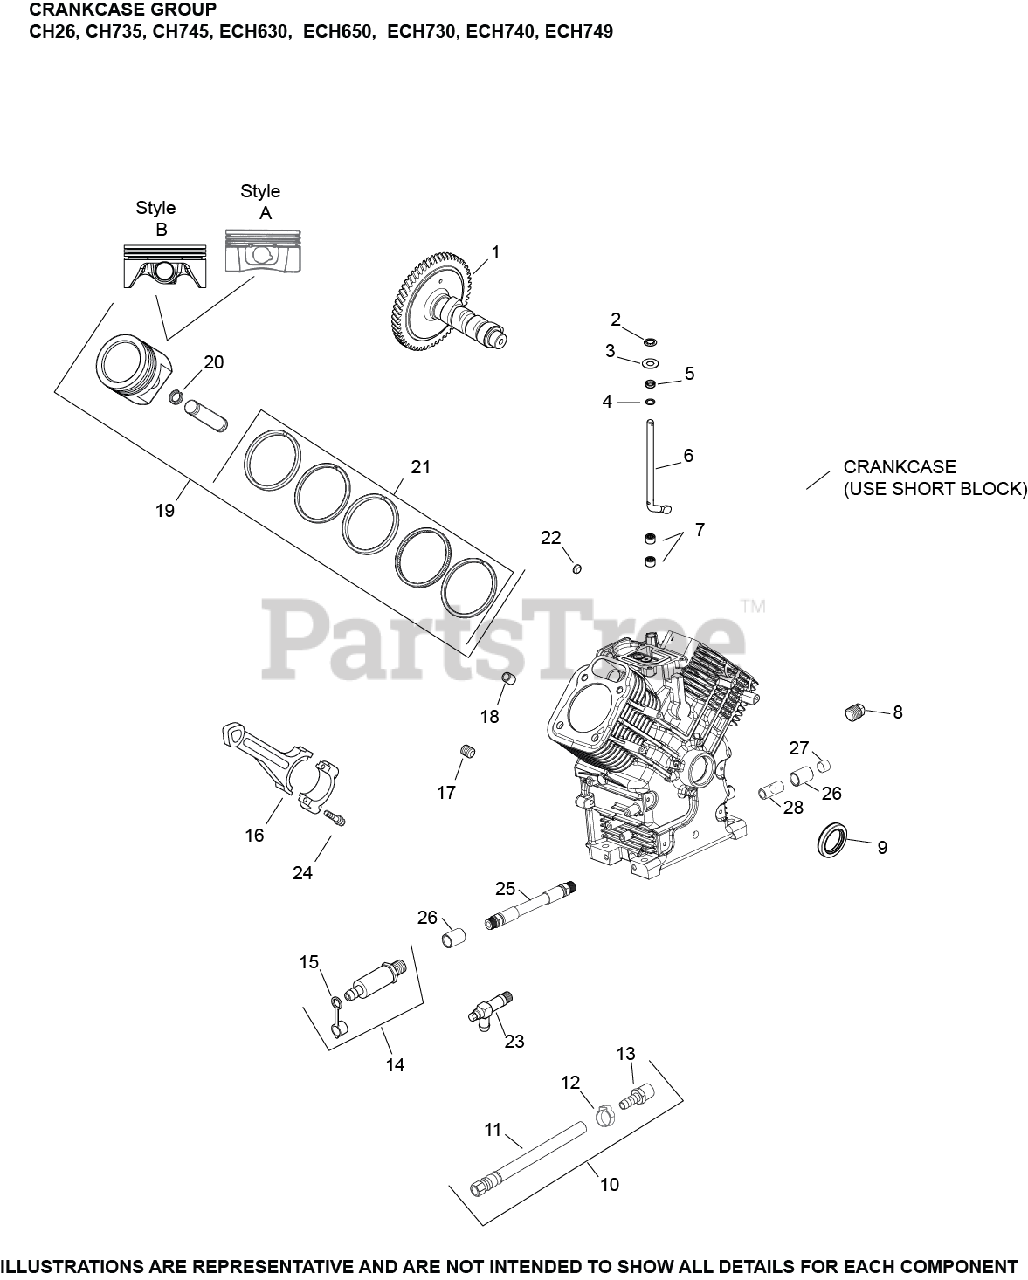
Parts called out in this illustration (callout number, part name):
1	KIT, CAMSHAFT
2	RETAINER, RING
3	WASHER, FLAT 9 MM
4	WASHER, FLAT 11/32"
5	SEAL, GOVERNOR CROSS SHAFT
6	SHAFT, GOVERNOR CROSS
7	BEARING, NEEDLE
8	PLUG, HD PIPE 3/8"
9	SEAL, OIL (HELIX LIP)
16	KIT, CONNECTING ROD ASSEMBLY USE 25 067 04-S
16	KIT, CONNECTING ROD ASSEMBLY (.25 mm)
17	PLUG, CTSK PIPE 1/8"
18	PIN, LOCATING
19	PISTON W/RINGS (STYLE B)(STD) - RING SET 24 108 26-S
19	PISTON W/RINGS (STYLE B)(.08) - RING SET 24 108 27-S
19	PISTON W/RINGS (STYLE B)(.25) - RING SET 24 108 28-S
19	PISTON W/RINGS (STYLE B)(.50) - RING SET 24 108 29-S
20	RETAINER, PISTON PIN
21	RING SET (STYLE B) (STD)1.2MM TOP RING THICKNESS
21	RING SET (STYLE B) (.08)1.2MM TOP RING THICKNESS
21	RING SET (STYLE B) (.25)1.2MM TOP RING THICKNESS
21	RING SET (STYLE B) (.50)1.2MM TOP RING THICKNESS
5213909-S	PLUG, CUP
